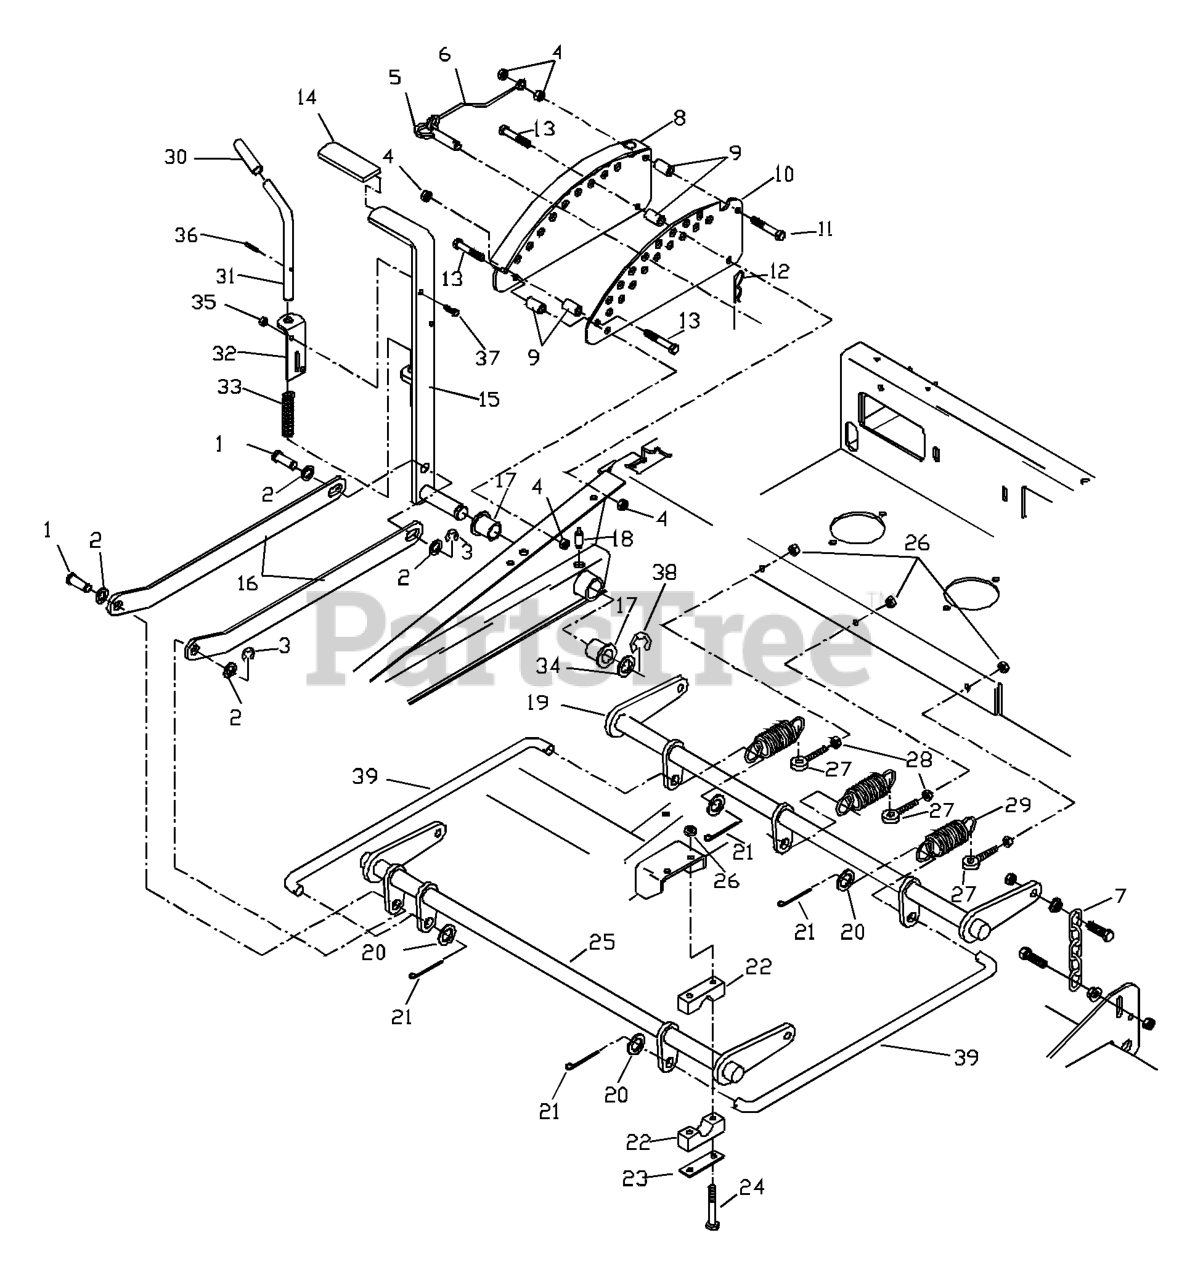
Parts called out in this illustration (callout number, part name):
1	CLEVIS PIN
2	BUSHING
3	E-RING 5/8
4	NUT 3/8C CENTERBLOCK
7	LIFT CHAIN
8	ADJ. PLATE WLDMNT
9	DECK LIFT SPACER
10	ADJ. PLATE PAINTED
11	HCS 3/8C X 2 1/2
12	HAIRPIN #4
13	HCS 3/8C X 2 1/4
15	LIFT LEVER WLDMT
16	LIFT LINKAGE,PAINTED
17	BUSHING, FLANGED
18	GREASE ZERK LONG
19	LIFT SHAFT
20	WASHER 5/8 FLAT
21	COTTER PIN
22	PILLOW BLOCK
23	REINFORCEMENT BAR
24	BOLT 5/16C X 2 1/2
25	FT. LIFT SHAFT
26	NUT 5/16C CENTERLOCK
27	EYEBOLT, RH
28	NUT 5/16C WHIZ
29	DECK LIFT SPRING
32	PIN MT, UPPER
34	BSHG .875 X 1.375 X .074 ZD
35	NUT 1/4C CENTER LOCK
36	ROLL PIN 3/16 X 1-1/4 ZD
37	HCS 1/4C X 3/4 HCS
38	E-RING 7/8
39	CONNECTING LINK
